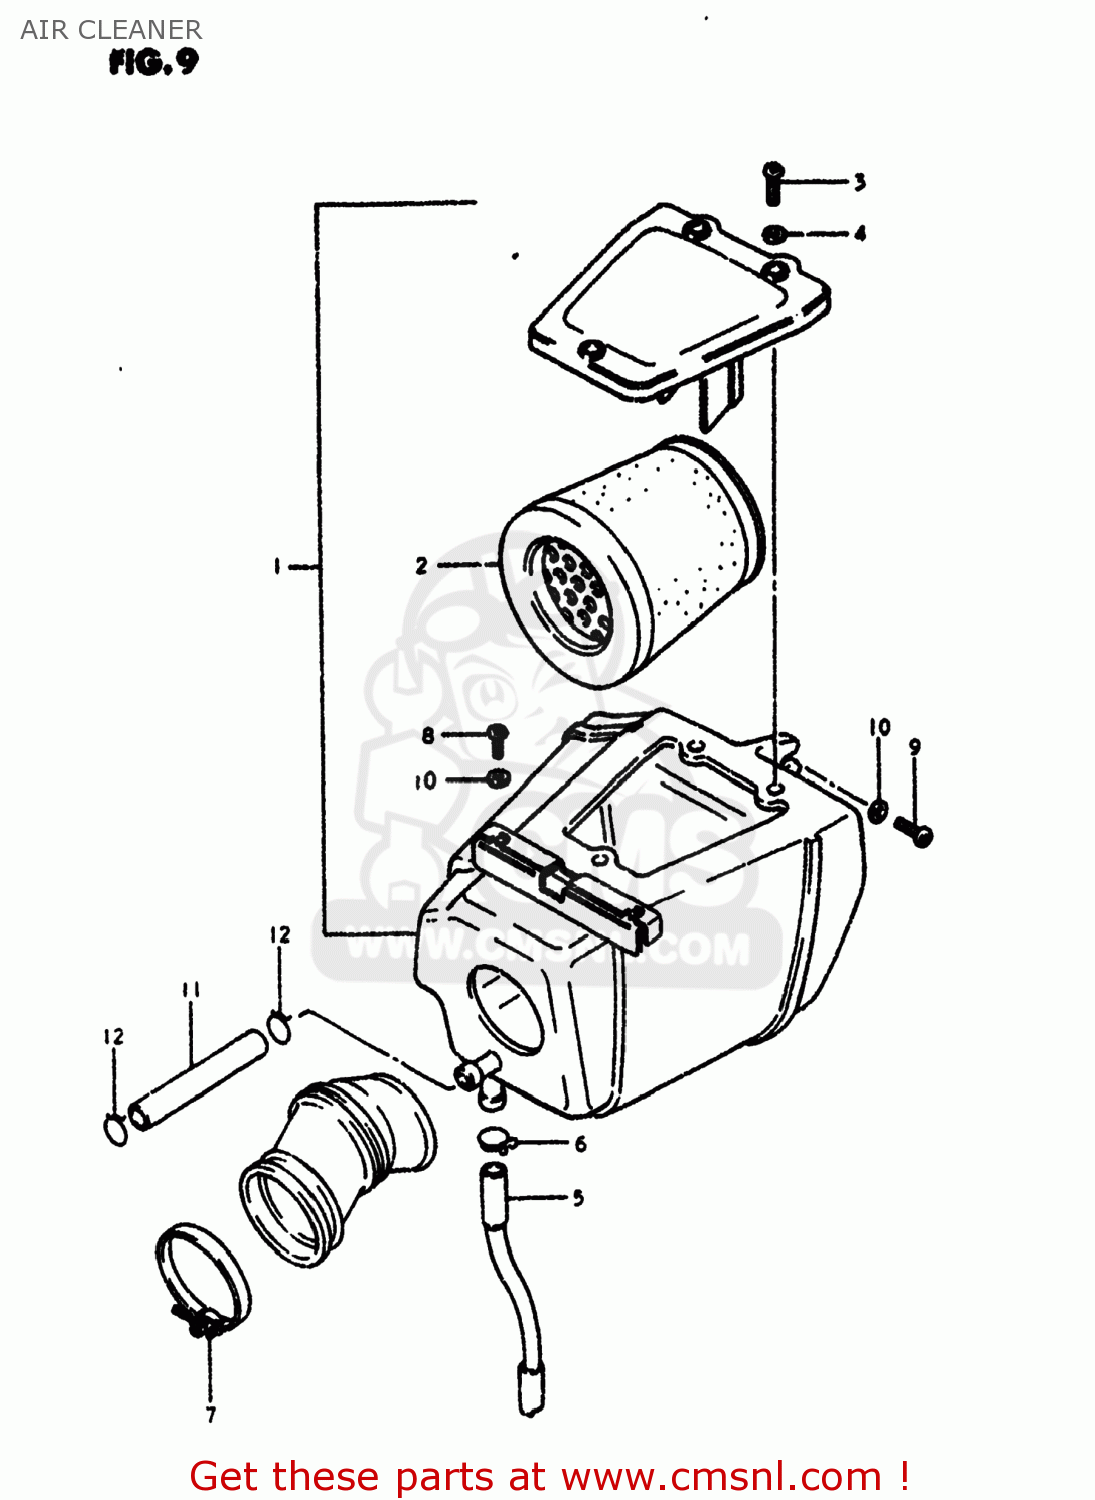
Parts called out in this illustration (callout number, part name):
1	CLEANER ASSEMBLY,AIR
2	FILTER,AIR CLEANER
3	SCREW
4	WASHER
5	DRAIN TUBE
6	CLAMP
7	CLAMP
8	SCREW 6X12
9	SCREW
10	WASHER
11	HOSE
12	CLIP
